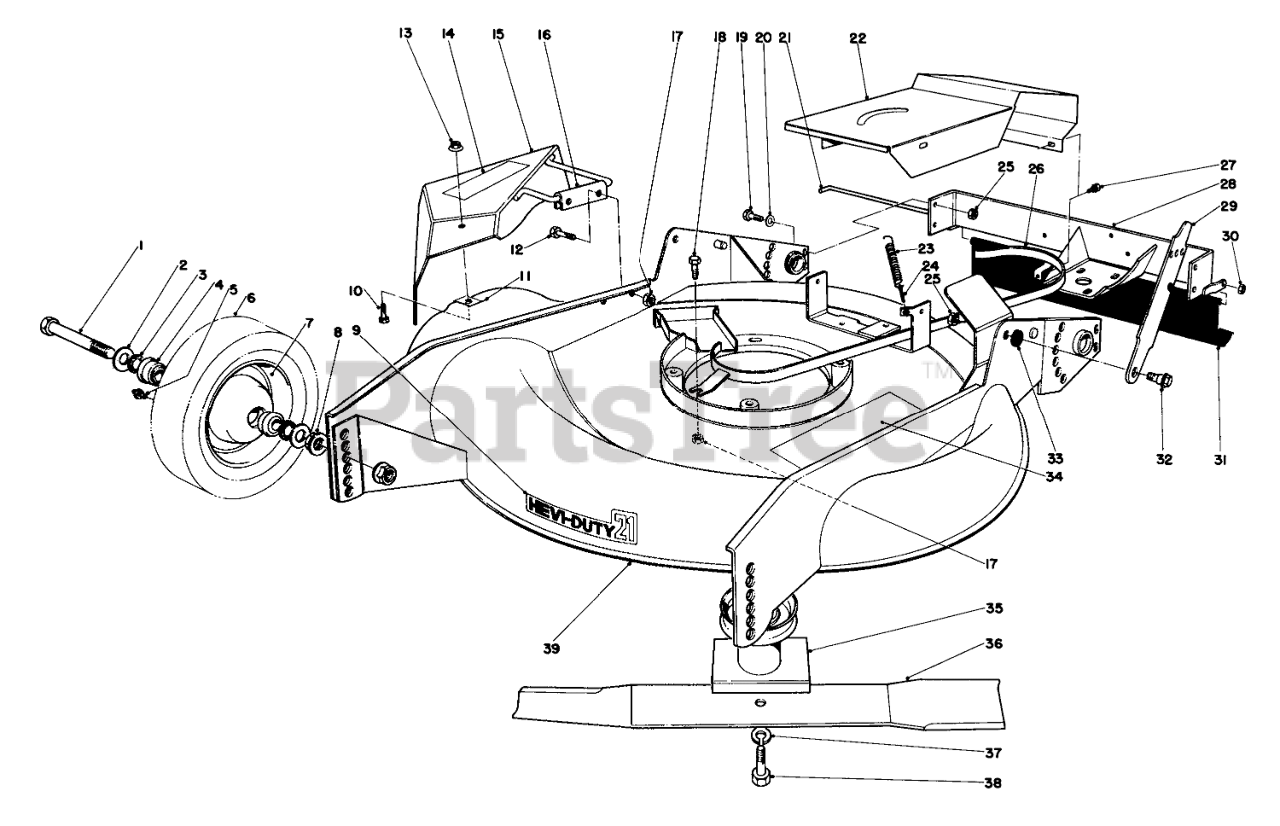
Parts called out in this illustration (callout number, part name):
1	SCREW-HH
2	WASHER-FLAT
3	FELT WASHER
4	BEARING-BALL
5	FITTING-GREASE
7	Wheel & Tire Assembly (Incl. Ref. # 4-6)
8	NUT-HF
9	Decal Hevi-Duty 21
10	SCREW-HH
11	NUT-SPEED
12	SCREW-HH
13	NUT-LOCK, HHF
14	Decal-Deflector
15	Deflector
16	Hinge-U Bracket
17	NUT-LOCK
18	SCREW-HH
19	SCREW-HH
20	WASHER-PLAIN
21	SHIELD ROD
22	Shroud
23	IDLER SPRING
24	PIN-COTTER
25	Nut
26	Belt Guide
27	Screw
28	Support-Gear Case
29	Latch
30	NUT-LOCK, NI
31	Rear Safety Shield
32	SCREW-SHOULDER
33	SPACER
34	Decal-Saftey Instruction
35	BLADE RETAINER W A
36	BLADE
37	WASHER-LOCK
38	Place Bolt
39	Housing (Incl. Ref. #9 & 34)
